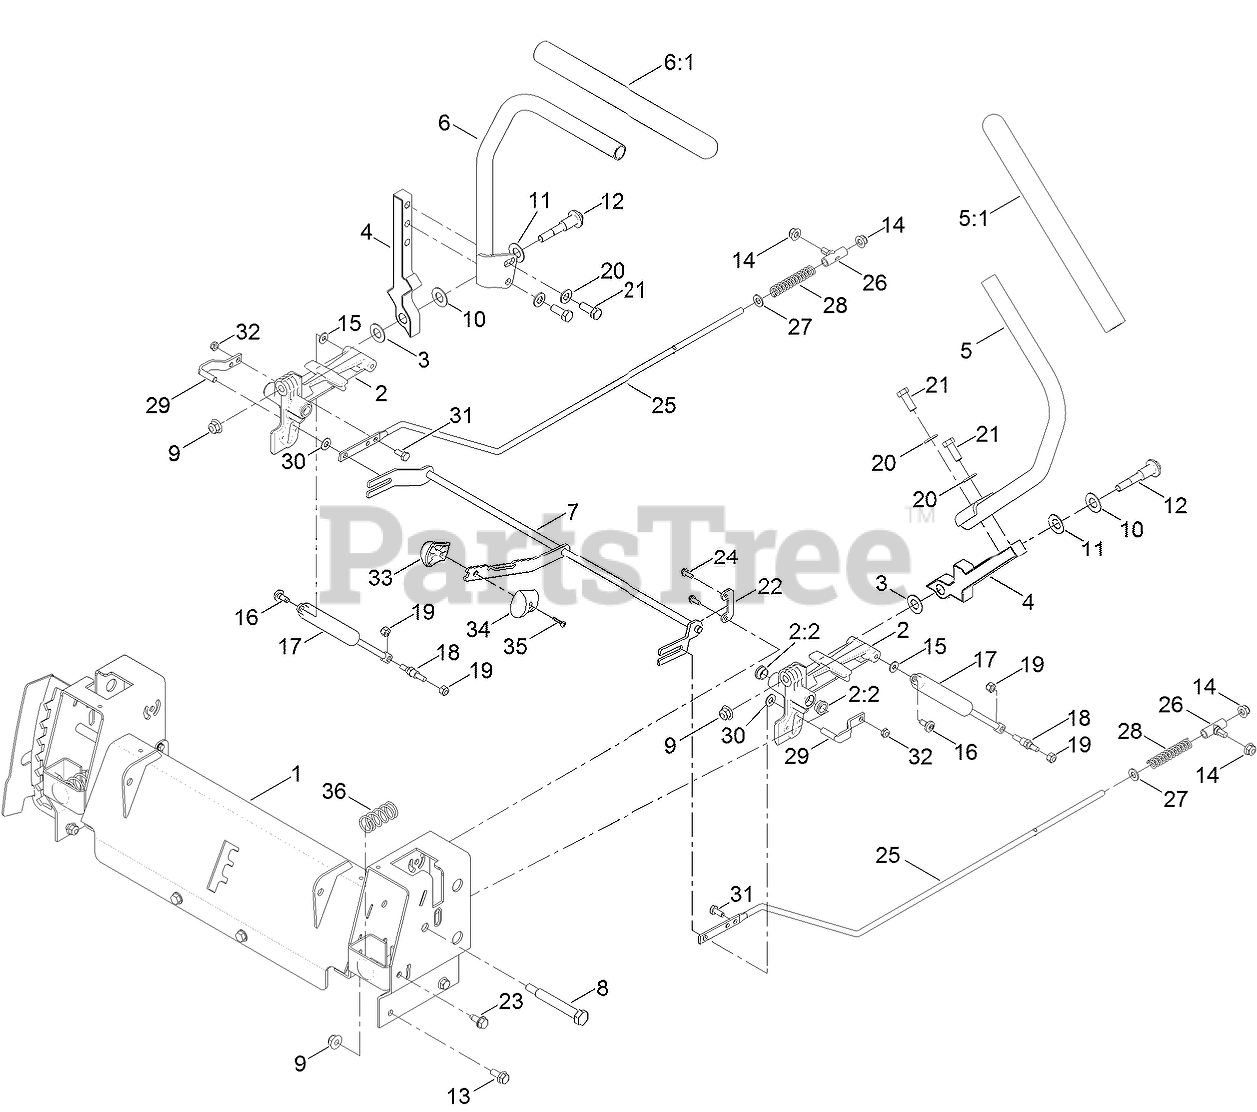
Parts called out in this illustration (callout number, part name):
1	CONTROL BOX ASM
2	ACTUATOR ARM ASM
2:2	BUSHING-FLANGE
3	WASHER-NYLON
4	ARM-CONTROL
5	HANDLE-CONTROL, LH
6	HANDLE-CONTROL, RH
7	SPEED CONTROL ASM
8	BOLT-PIVOT
9	NUT-HF, NI
10	WASHER
11	WASHER-BELLEVILLE
12	BOLT-PIVOT
13	SCREW-HHF
14	NUT-HF, NI
15	WASHER
16	SCREW-SHOULDER
17	DAMPER
18	STUD-DAMPER
19	NUT-LOCK, NI
20	WASHER-FLAT
21	SCREW-HH
22	RETAINER
23	SCREW-HWHTF
24	SCREW-TAPTITE
25	ROD-HYDRO
26	MOUNT-ROD, HYDRO
27	WASHER-PLAIN
28	SPRING-RETURN, NEUTRAL
29	PIN-ROD, HYDRO
30	SPACER-NYLON
31	SCREW-HH
32	NUT-LOCK, NI
33	KNOB-RH
34	KNOB-LH
35	SCREW-PPH
36	SPRING-RETURN
